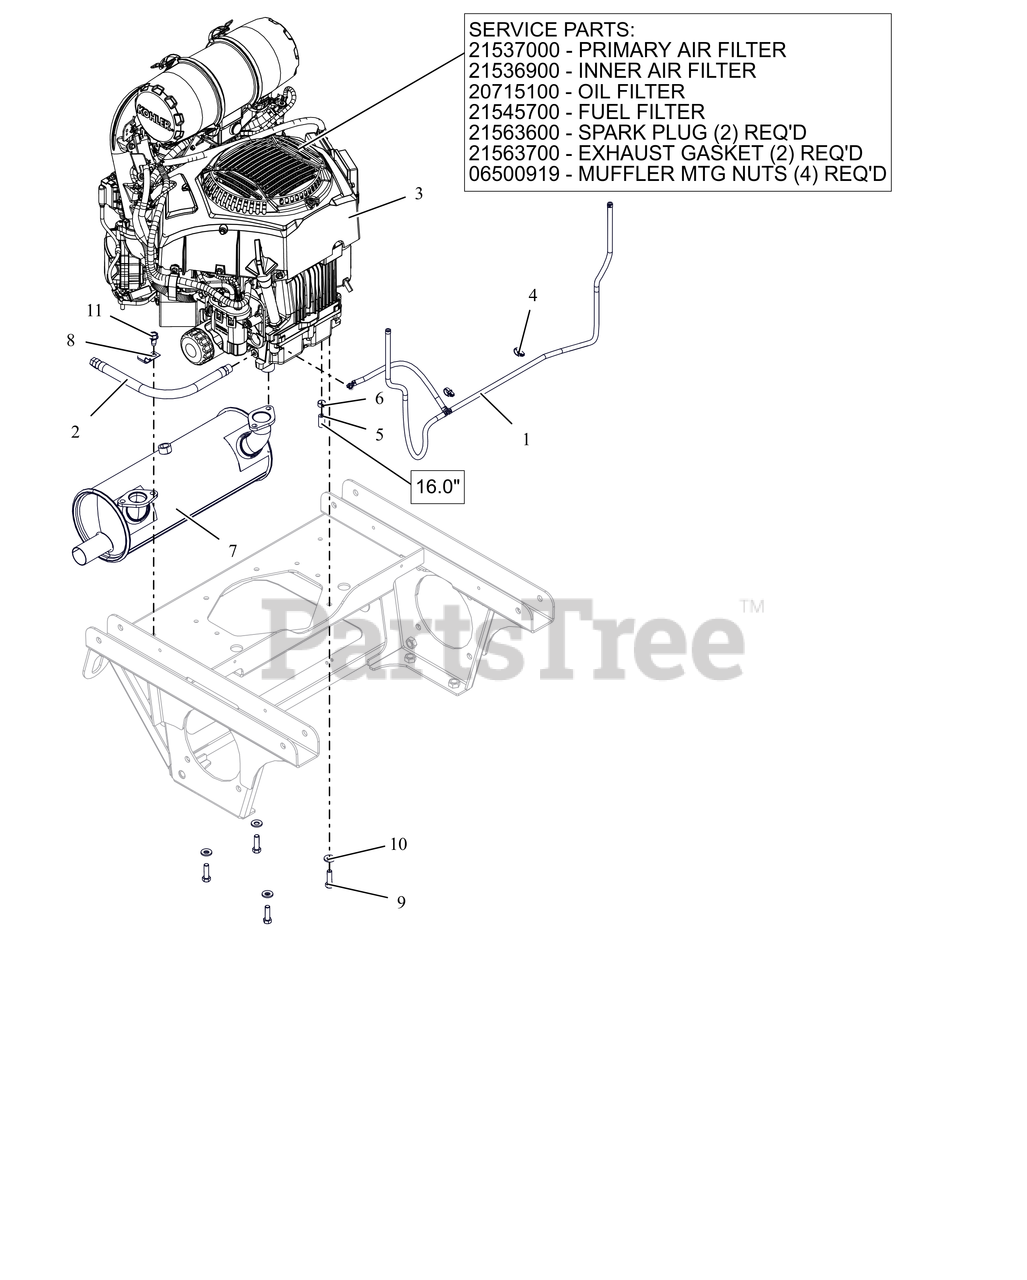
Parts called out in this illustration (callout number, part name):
1	ASM, KOHLER EFI VAPOR LINE
2	HOSE, OIL DRAIN
3	ENGINE, KOHLER ECV880-EFI
3	ELEMENT, OUTER PRIMARY
3	ELEMENT, INNER SAFETY
3	OIL FILTER KOHLER
3	FILTER-FUEL KOHLER COURAGE PRO
3	PLUG, SPARK
3	GASKET, EXHAUST
3	NUT-LK-TOP-FLG M8 ZCC
4	ROUTING CLIP (1/2" ID)
5	HOSE, .25 LOW-PERM BULK GAS
6	CLAMP, FUEL LINE
7	MUFFLER, KOHLER EFI
9	BLT, HEX .38-16X1.25 G5 ZCC NT
10	WASHER, 3/8" SPRING DISC
11	SCR,TAP .375-16X.75 HWH TR ZCC
